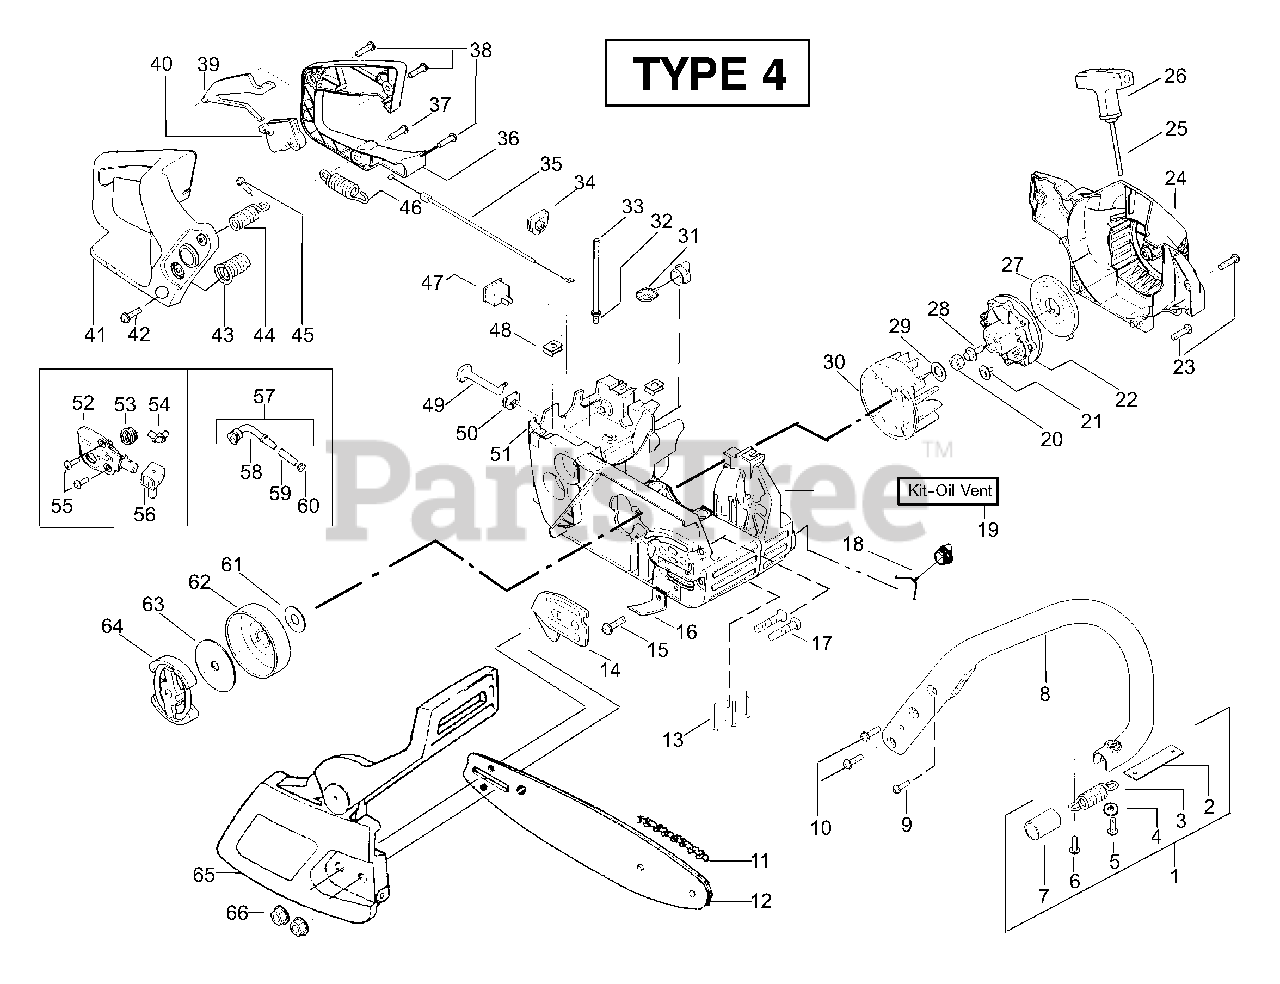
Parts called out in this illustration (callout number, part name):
1	Assy.-Isolator
2	Limiter Strap
3	Spring-Isolator
7	Sleeve-AV Spring
8	Handle-Front
11	Chain-16"
12	Bar-16" Quick Adjust
14	Plate-Bar Mounting
16	Chain Catcher
17	Bolt-Bar
18	Assy-Oil Cap
19	Kit-Oil Check Valve
20	Nut-Flywheel
22	Starter Pulley
24	Assy-Fan Housing
25	Kit-Rope
26	Handle-Starter
27	Spring-Recoil
29	Washer-Flywheel
30	Assy-Flywheel
31	Assy-Fuel Cap
32	Fitting-fuel line
33	Kit-Fuel line (large)
34	Grommet-Cable
35	Cable-Throttle
36	Cover-Rear Handle
39	Throttle Lockout
40	Trigger-Throttle
41	Handle-Rear
43	Assy. Isolator-lower
44	Kit-Isolator (Upper)
46	Spring-Isolator
47	Kit-Switch
48	Nut-"U"-Type
49	Knob-Choke
50	Grommet-Knob
51	Assy-Chassis
52	Kit-Oil Pump
53	Gear-Worm Spring
54	Elbow-Oil Pickup
56	Seal Block
57	Assy-Oil Pickup
58	Pickup-Oiler
59	Filter-Oil
60	Plug-Oil Filter
61	Washer-Thrust
62	Assy.-Clutch Drum w/bearing
63	Washer-Clutch
64	Assy. Clutch
65	Assy-Chain Brake
66	Nut-Bar Mounting
